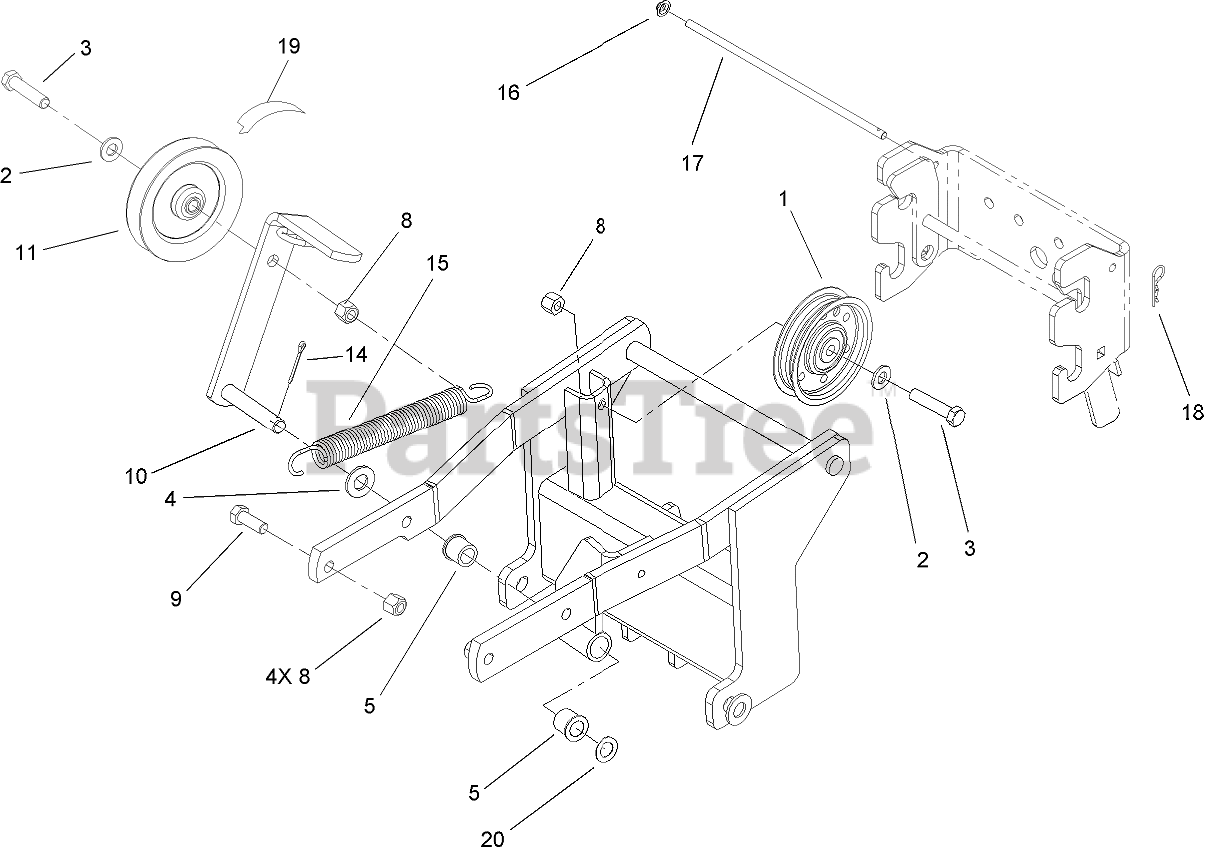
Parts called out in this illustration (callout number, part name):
1	PULLEY-IDLER, FLAT
2	WASHER-FLAT
3	SCREW-HH
4	WASHER-FLAT
5	BUSHING
8	NUT-LOCK, NI
9	SCREW-HH
10	IDLER ARM ASM
11	PULLEY-V, IDLER
14	PIN-COTTER
15	SPRING-EXTENSION
16	NUT-SPEED
17	ROD-STOP
18	PIN-HAIR
19	V-BELT, JACKSHAFT
20	WASHER
